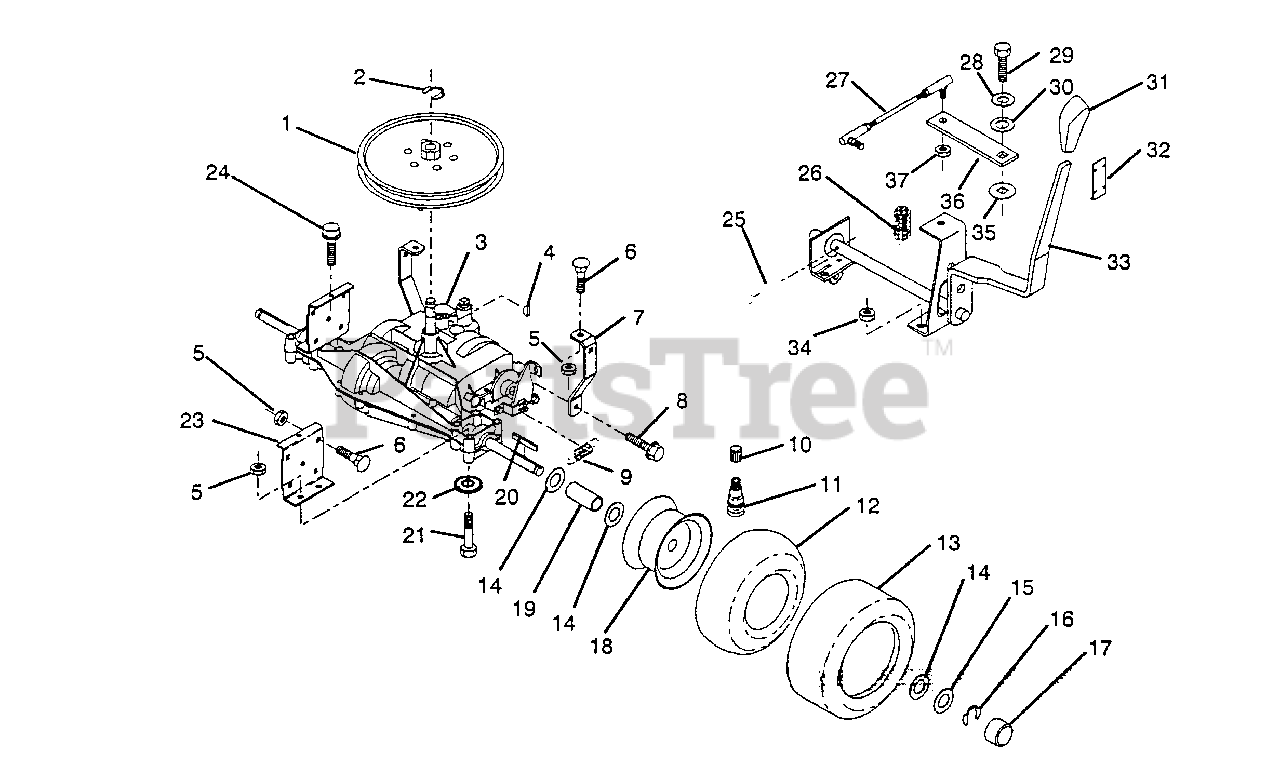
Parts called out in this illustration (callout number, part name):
2	Ring, Retainer
3	Transaxle, Peerless 6 Speed Model Number 930-028
4	Key, Woodruff #9
5	Nut, Crownlock 5/16-18
6	Bolt, Carriage 5/16-18 UNC x 3/4
7	Strap, Torque
8	Screw, Hex Thdrol. 5/16-18 x 1/2
9	Spring, Brake
10	Cap, Valve
11	Stem, Valve
13	Tire, Rear
14	Washer 25/32 x 1-1/4 x 16 Ga.
15	Washer 25/32 x 1-5/8 x 16 Ga.
20	Key, Square
21	Bolt, Fin, Hex 5/16-18 x 2-1/2
22	Washer 11/32 x 11/16 x 16 Ga.
23	Bracket, Transaxle
24	Screw, 5/16-18 x 3/4
25	Pin, Cotter 1/8 X 1
26	Spring, Extension
27	Link, Shift
28	Washer, Lock Hvy. Helical Spring 1/4
29	Bolt, Fin, Hex 1/4-28 UNF x 3/4 Gr. 8
30	Washer 9/32 x 3/4 x 10 Ga.
31	Knob, Shift Control
32	Retainer, Knob
33	Assembly, Shift Handle
34	Nut, Keps 5/16-18
35	Washer, Shift Plate
36	Arm, Shift
37	Nut, Hex Nylon 5/16-24
